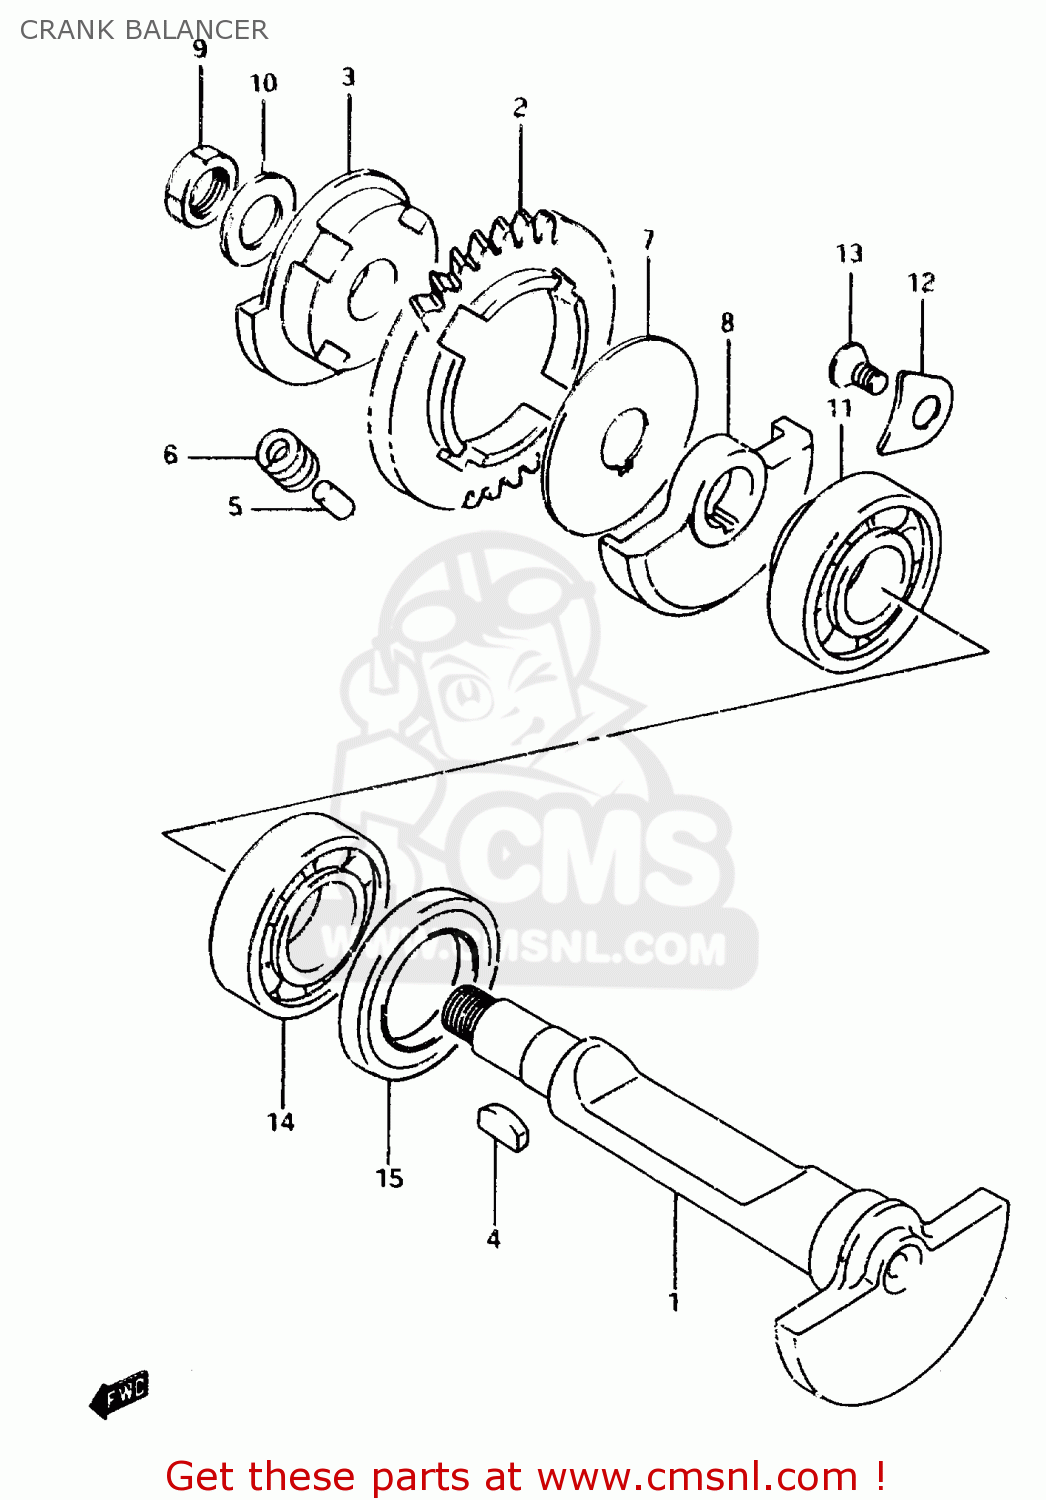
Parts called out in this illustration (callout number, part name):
1	SHAFT, CRANK BALANCER
2	GEAR, BALANCER DRIVEN
3	RACE, DRIVEN GEAR INNER
4	KEY 4MM
5	PIN(5X8.8)
6	SPRING
7	WASHER
8	WEIGHT, CRANK BALANCER RH
9	NUT
10	WASHER
11	BEARING(15X42X13)
12	RETAINER,BEARING
13	SCREW(6X12)
14	BEARING(20X42X12)
15	SEAL,OIL(25X42X6)
